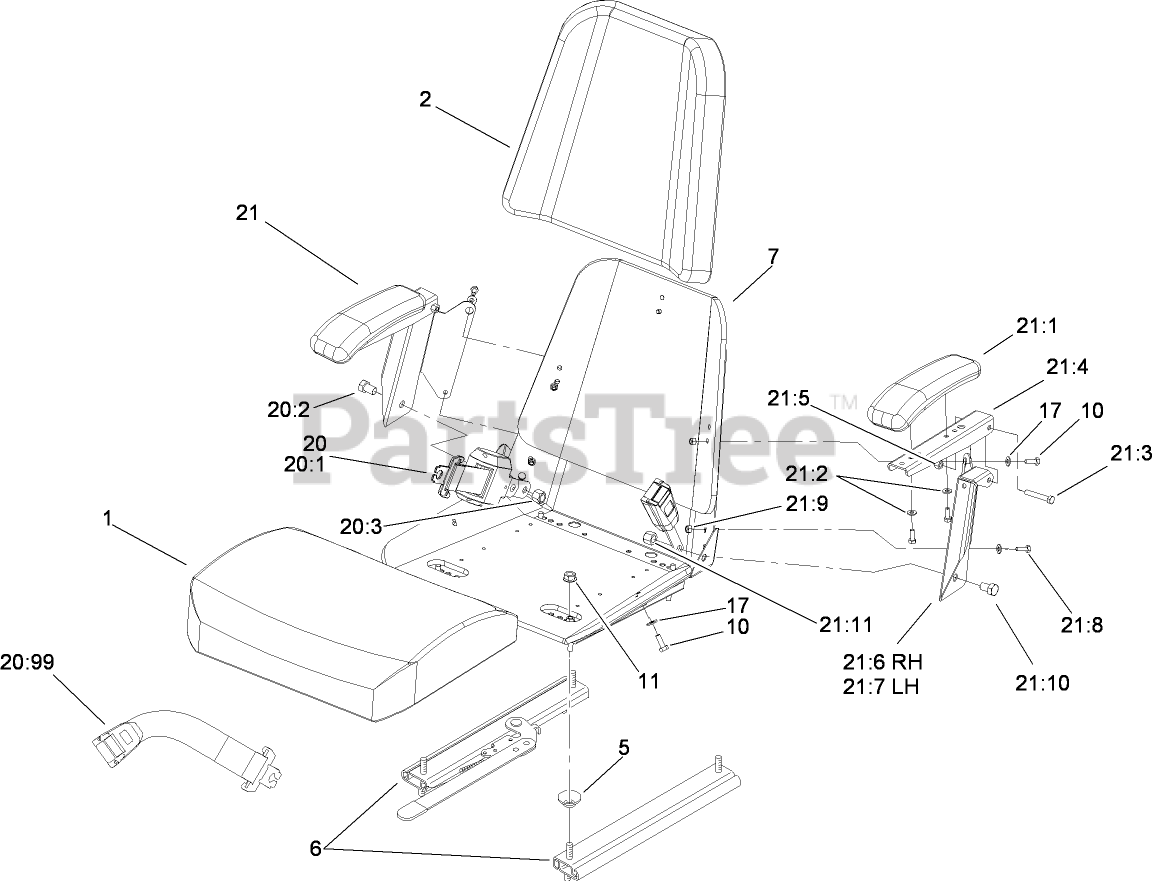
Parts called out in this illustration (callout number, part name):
1	CUSHION-SEAT, BOTTOM
2	CUSHION-SEAT, BACK
5	SPACER-TRACK
6	TRACK-SEAT
7	FRAME-SEAT
10	SCREW-HH
11	NUT-HF
17	WASHER-FLAT
20	RETRACTABLE SEATBELT KIT
20:1	SEATBELT-RETRACTABLE
20:2	SCREW-HH
20:3	NUT-LOCK
20:99	SEAT BELT EXTENSION KIT
21	ARMREST KIT
21:1	CUSHION-REST, ARM
21:2	WASHER-FLAT
21:3	SCREW-HH
21:4	CHANNEL-ARMREST
21:5	NUT-HEX, SIDE DEFORM
21:6	Bracket-Armrest, RH
21:7	Bracket-Armrest, LH
21:8	SCREW-HH
21:9	NUT-LOCK, NI
21:10	SCREW-HH
21:11	NUT-LOCK, NI
